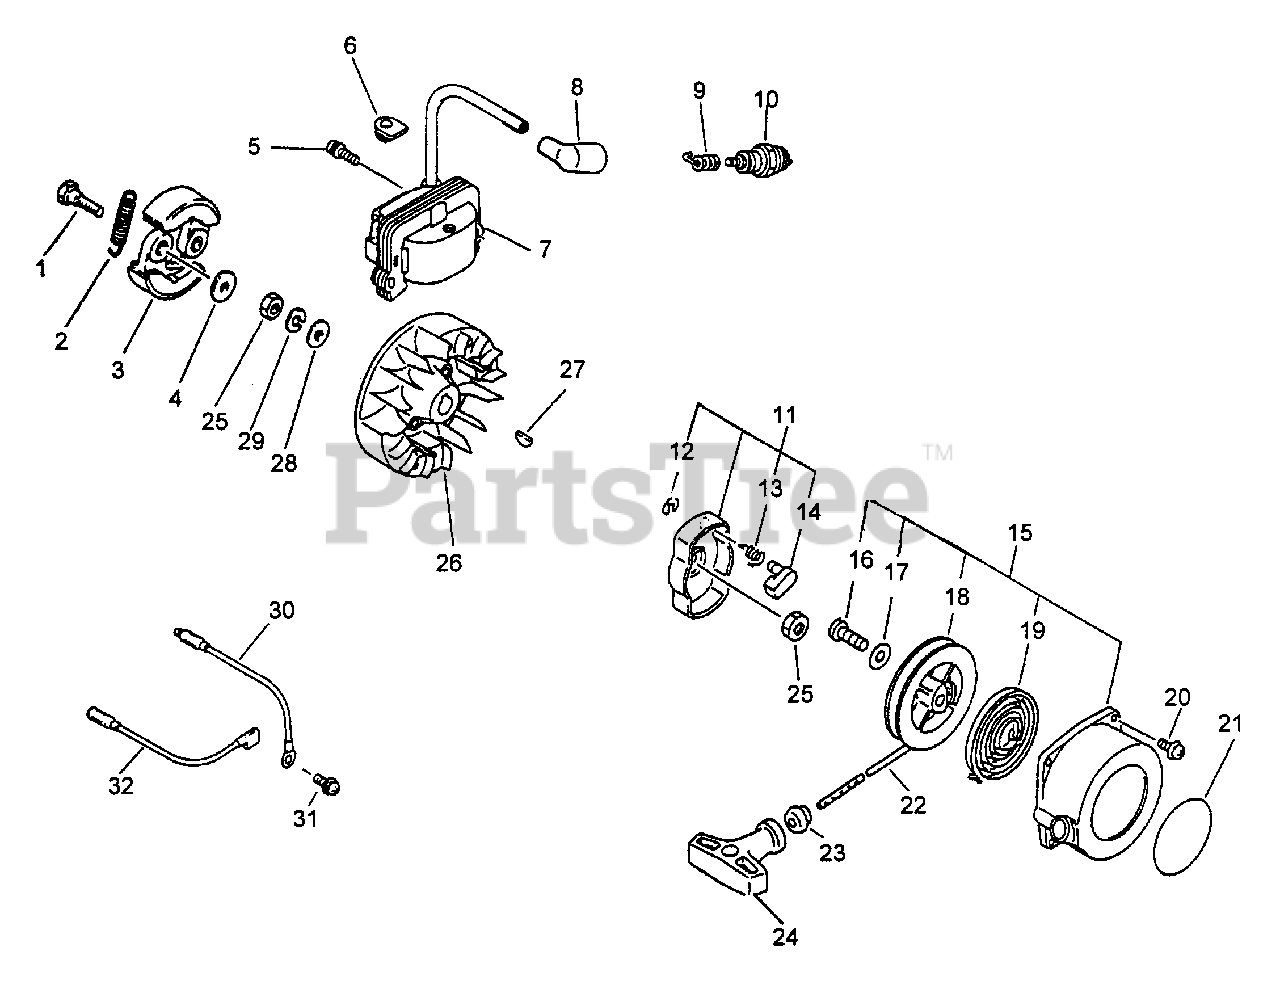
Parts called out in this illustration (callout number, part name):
1	BOLT, CLUTCH M6
2	SPRING, CLUTCH
3	SHOE, CLUTCH
4	WASHER 6.2×19×1.0
5	BOLT 5×20
7	COIL, IGNITION
8	CAP, SPARK PLUG
9	TERMINAL, SPARK PLUG
10	SPARK PLUG - BPM7A
11	PAWL ASSY, STARTER
12	E-RING 4
13	SPRING, RETURN
14	PAWL, STARTER
15	STARTER ASSY
18	REEL, ROPE
19	SPRING, RECOIL
20	BOLT 4×14
21	LABEL, ECHO
22	BULK STARTER ROPE - Ø 4.0 MM×61 M
23	GUIDE, ROPE
24	GRIP, STARTER
25	NUT 8×1.25
26	FLYWHEEL
27	KEY, WOODRUFF
28	WASHER 8.5×16×1.2
29	WASHER, SPRING 8
30	LEAD - GROUND
31	SCREW 5×10
32	LEAD 170 MM
